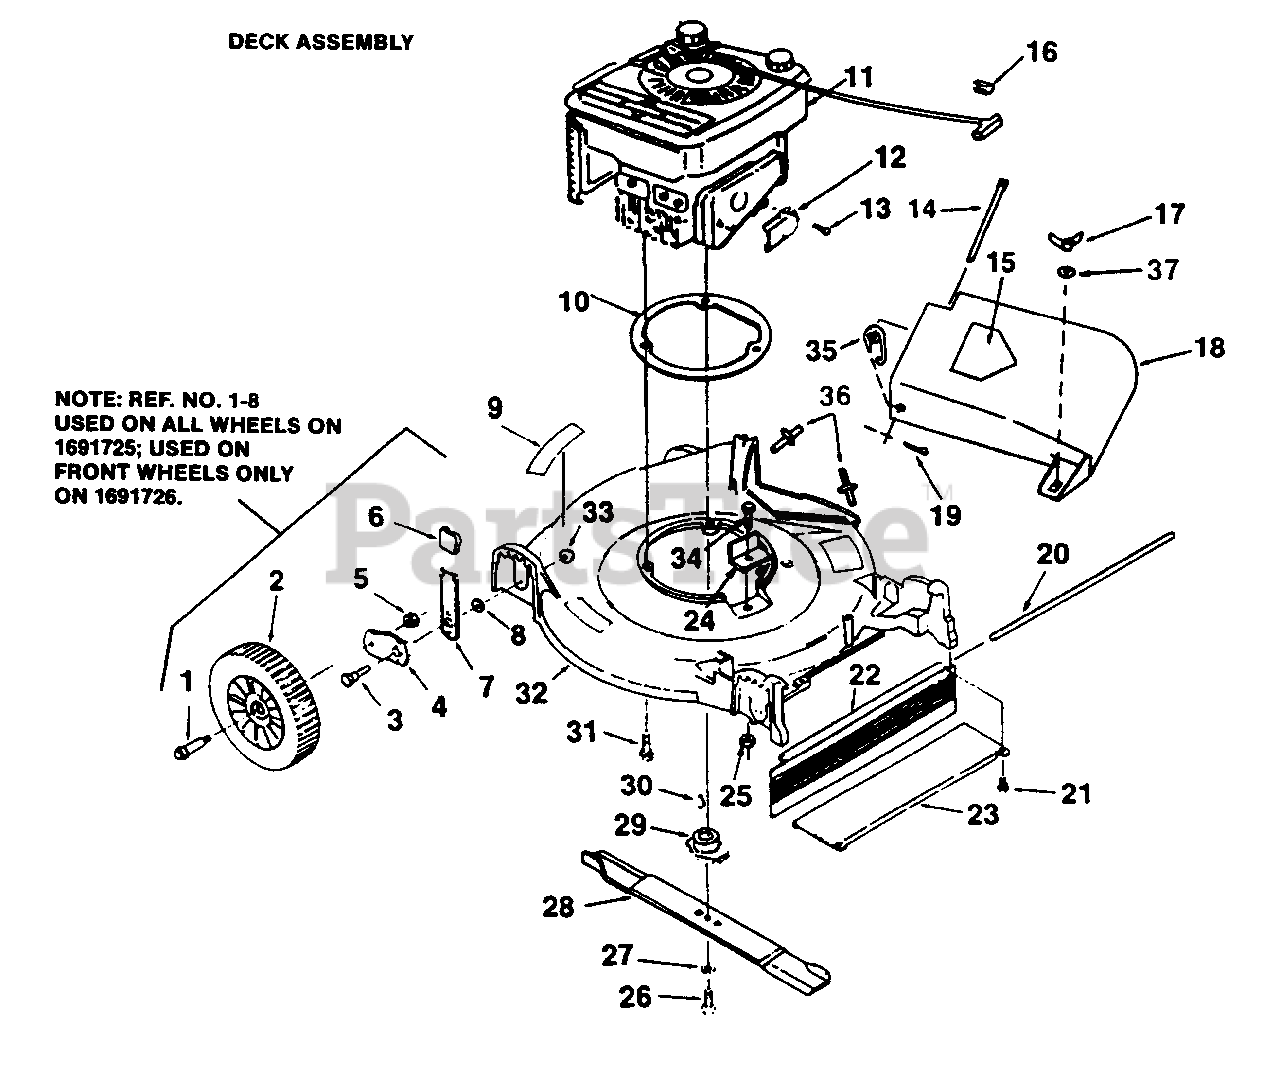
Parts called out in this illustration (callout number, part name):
1	BOLT & NUT ASSY. (Incl. Ref. No. 5)
2	WHEEL & TIRE (Qty. 2, Mfg. No. 1691726)
3	BOLT, Hex Hd., 5/16-18 (Qty. 2, Mfg. No. 1691726)
4	ARM, Wheel Adjusting (Qty. 2, Mfg. No. 1691726)
5	NUT, Hex, 3/8-16
9	DECAL, 20"
10	RING, Engine
12	DEFLECTOR
13	SCREW, Hex Hd., 8-32 x 3/8"
14	PIN, Hinge
15	DECAL, Warning
16	ROPE STOP
18	CHUTE & LATCH ASSY.
19	PIN, Cotter, 3/32 x 3/4"
21	SCREW, Hex Washer
22	FLAP, Drag
23	COVER, Rear (Mfg. No.1691725 Only)
24	COVER, Belt Opening (Mfg. No. 1691725 Only)
25	NUT, Hex, 1/4-20
26	SCREW, Hex Hd., 3/8-24 x 1"
27	WASHER, Lock, 3/8"
30	KEY
31	SCREW, Hex Hd., 3/8-16 x 1-1/2"
32	DECK (Mfg. No. 1691725)
32	DECK (Mfg. No. 1691726)
33	NUT, Flange, 5/16-18
34	SCREW, Hex Hd., 1/4-20 x 1/2" (Mfg. No. 1691725 Only)
35	SPRING CLIP
37	WASHER, Flat, 1/4"
